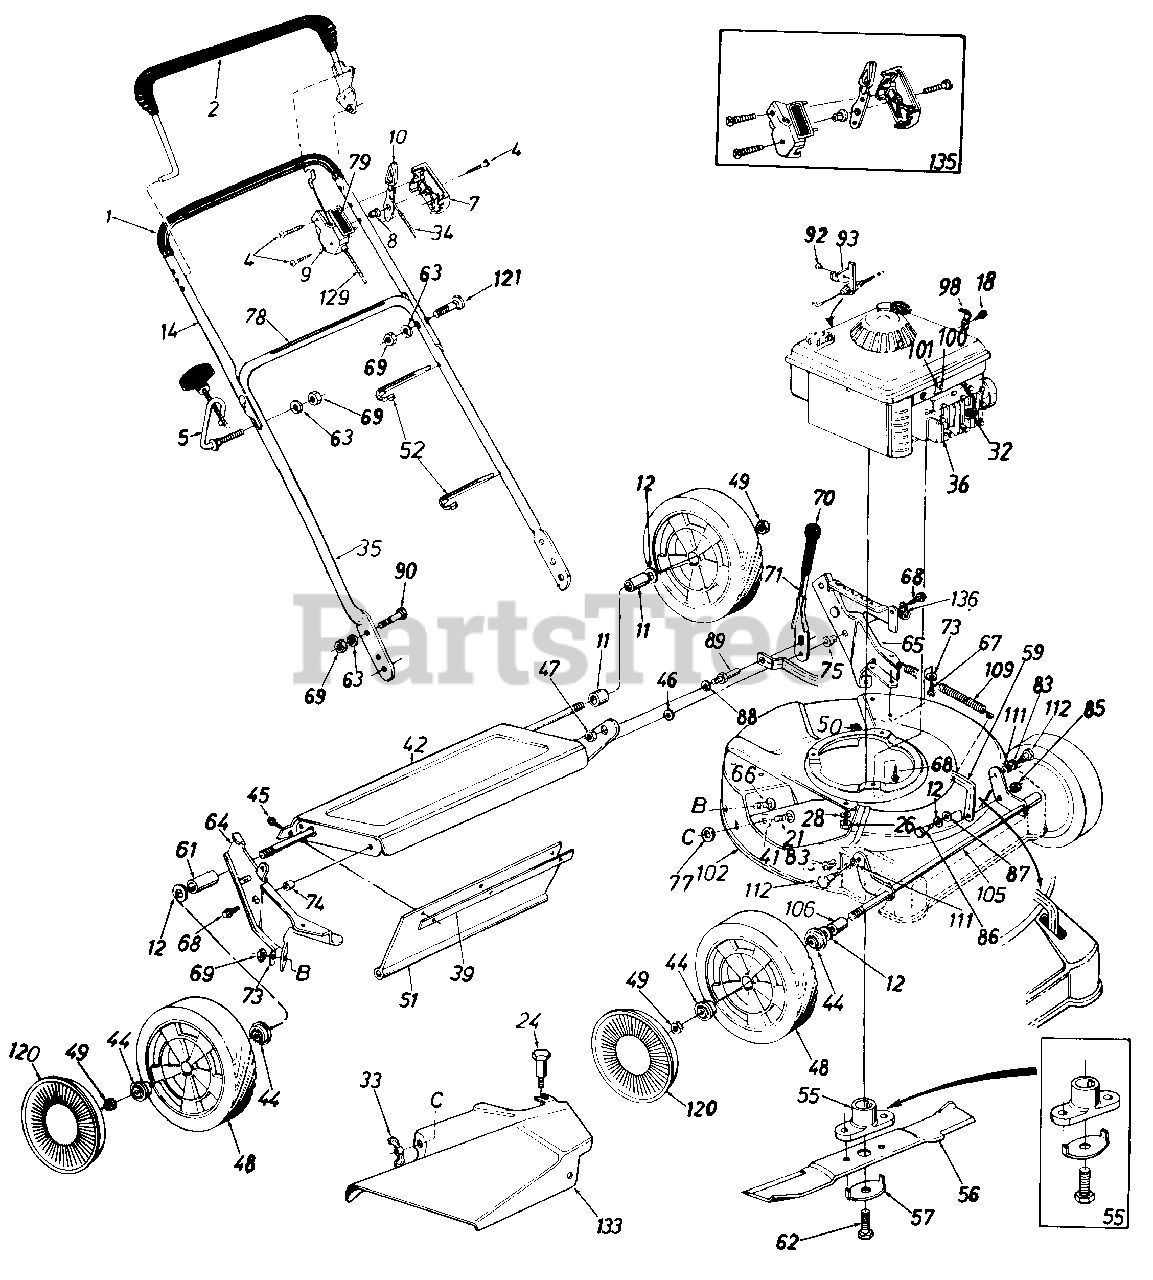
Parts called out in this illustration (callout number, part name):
1	Grip
2	Control Handle Ass'y.-L.H.
4	Truss Mach. Scr. #12 x 1.50" Lg.
5	Rope Guide Bolt
7	Control Panel Half
8	Control Disc Pin
9	Clutch Panel Half
10	Throttle Control Lever
11	Spacer .526" I.D. x .690" O.D x .640" Lg.
12	Fl-Wash. .510" I.D. x .75"
14	Upper Handle
18	Hex B-Tap Scr. #10 x .38"
21	Carriage Bolt 1/4-20 x .62"
24	Shoulder Bolt .312 Dia. x .18 Lg. Special
26	Hex Nut 1/4-20 Thd.
28	L-Wash. 1/4" I.D.
32	Spark Plug Insulator
33	Wing Nut w/Washer
34	Throttle Control Wire 58"
35	Lower Handle
36	Engine
39	Retaining Strip
41	Fl-Wash. .344" I.D. x .62"
45	Hex AB-Tap Scr. 1/4 x .62"
46	Fl-Wash. .38" I.D. x 1.0"
47	Hex Jam Nut 3/8-24 Thd.
48	Wheel Ass'y.-Comp. 8" x 2"
49	Hex L-Nut 1/2-20 Thd.
51	Rear Flap 3.75" x 17.30" Lg.
52	Cable Tie
55	Blade Adapter Kit
56	21n Blade
57	Blade Bell-Wash. .44" I.D. x 2.38"
59	Height Adj. Connecting Arm
61	Sleeve .526" I.D. x .69"
62	Hex Bolt 3/8-24 x 1.5" Lg. (Grade 5)
63	L-Wash. 5/16" I.D.
64	R.H. Handle Wheel Brkt. Ass'y.
65	L.H. Handle Wheel Brkt. Ass'y.
66	Carriage Bolt 5/16-18 x .62"
67	Hex Wash. Hd. B-Tap Scr. 5/16-1 8
68	Hex Wash. Hd. TT-Tap Scr. 3/8-1 6
69	Hex Nut 5/16-18 Thd.
71	Height Adj. Lever
73	Bell-Wash. 5/16" I.D.
74	Spacer .383" I.D. x .503" O.D.
75	Shld. Spacer .500" Dia.
77	Bolt Retainer 1/4 X .50" O.D.
78	Instruction Label
79	Control Label
83	Flanged Nyliner Brg.
85	Hex Jam Nut 3/8-16 Thd.
86	Shld. Bolt .50" Dia. x .295"
87	Bell-Wash. .515" l.D. x 1.0" O.D.
88	L-Wash. 3/8" I.D.*
89	Shld. Pin 3/8-24 x 1.43" Lg.
90	Truss Mach. Scr. 5/16-18 x .75"
93	Cable Bracket
98	Cable Clamp
100	Hex B-Tap Scr. #10 x .62" Lg.
106	Sleeve .526" I.D. x .690" O.D. x .880" Lg.
109	Extension Spring 8" Lg.
111	Intern. L-Wash. 3/8 I.D.
112	Shld. Bolt .575" Dia. x .42"
120	Hub Cap
121	Curved Carr. Bolt 5/16-18 x 1.38" Lg.
129	Control Cable 46" Lg.
133	Side Chute Deflector Ass'y.
135	Kit-Control Housing Comp.
